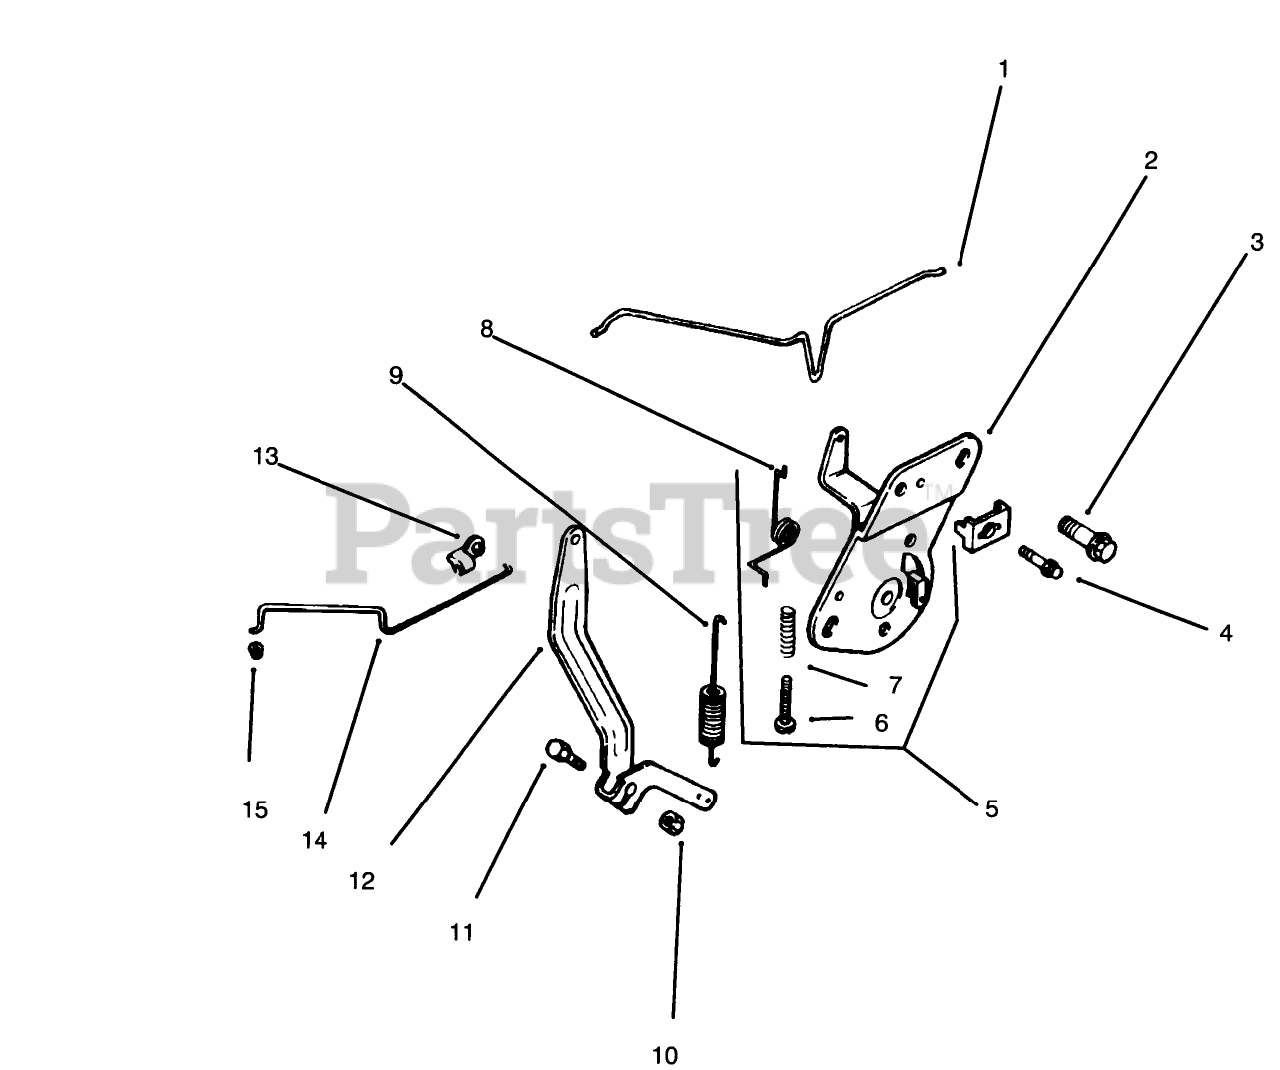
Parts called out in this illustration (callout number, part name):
1	Linkage-Choke
5	Control-Speed (incl Ref.#6-8)
7	Spring
8	Spring-Choke
9	Spring-Governor
12	Lever-Governor (Only On: 72042, 72063, 72062, 72043)
13	Bushing
14	Linkage-Throttle (Only On: 72042, 72063, 72062, 72043)
15	Bushing
